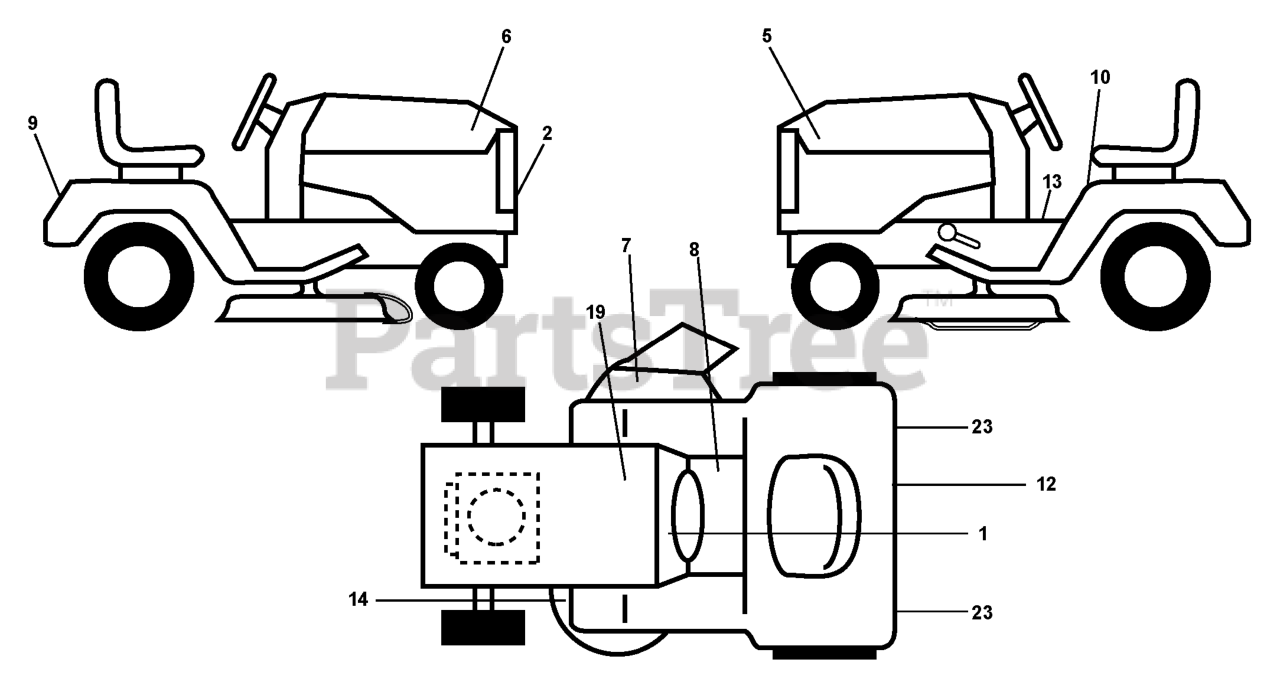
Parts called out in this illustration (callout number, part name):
2	DECAL.GRILLE.HUSQ
5	DECAL, HOOD LH GTH220 HYDRO
6	DECAL HOOD RH GTH220 HYDRO
7	DECAL WARNING (ENGLISH/FRENCH)
8	DECAL PARK BRAKE
9	Decal, Fender
10	DECAL CAUTION
12	DECAL D-BAR
19	DECAL BTRY SYMBOLS
23	REFLECTOR-TAIL YT
